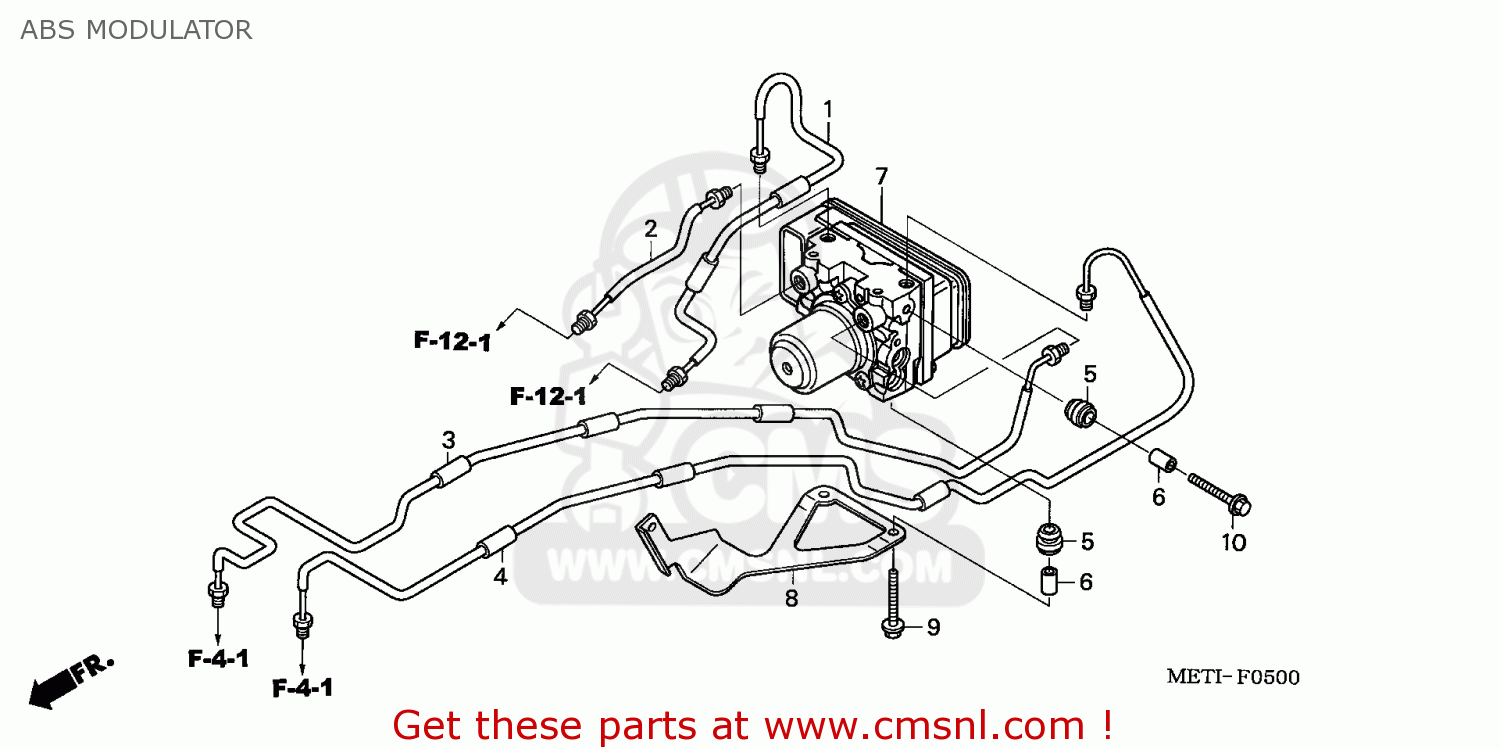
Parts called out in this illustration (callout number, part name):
1	PIPE A,RR BRK MAI
2	PIPE B,RR BRK MAI
3	PIPE A,FR BRK
4	PIPE B,FR BRK
5	RUBBER,MOUNT
6	COLLAR
7	MODULATOR ASSY,AB
8	STAY,RR BRK PIPE
9	BOLT,FLANGE,6X25
10	BOLT-WASHER,6X25
